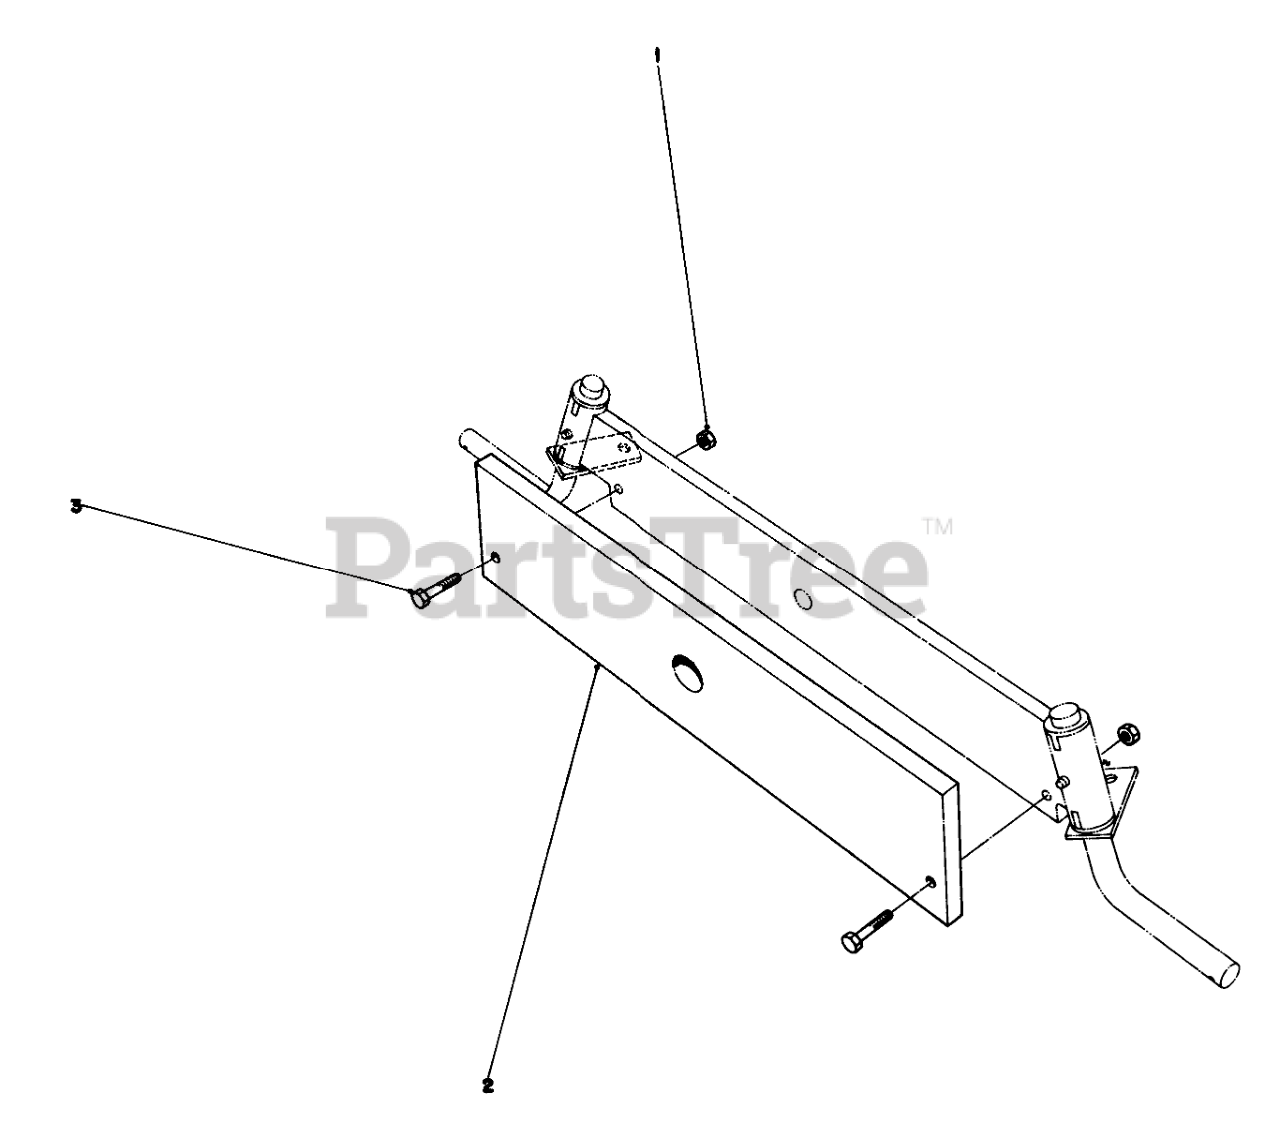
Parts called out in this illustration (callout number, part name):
1	NUT-LOCK, CONE
2	COUNTERWEIGHT B
3	SCREW-HH
